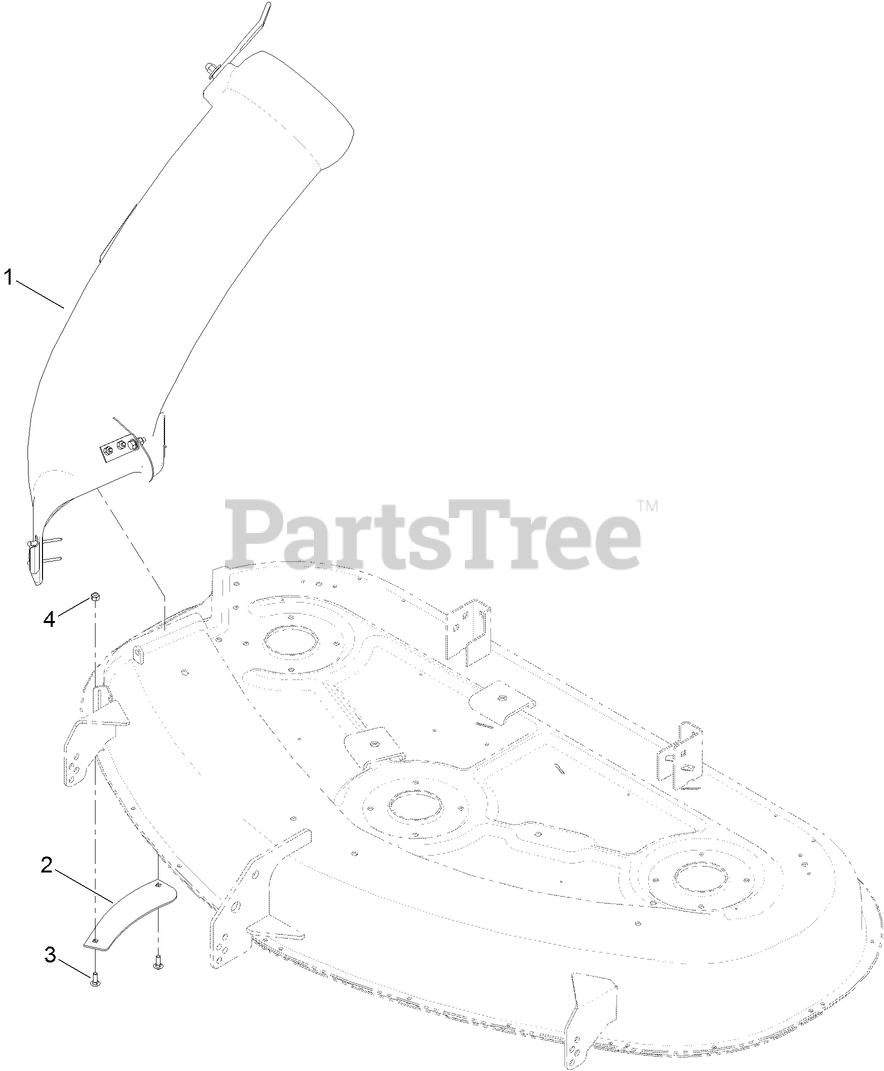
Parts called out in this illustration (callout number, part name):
1	50 INCH CHUTE ASM
2	BAFFLE-BLOWOUT
3	BOLT-CARR
4	NUT-LOCK, NI
